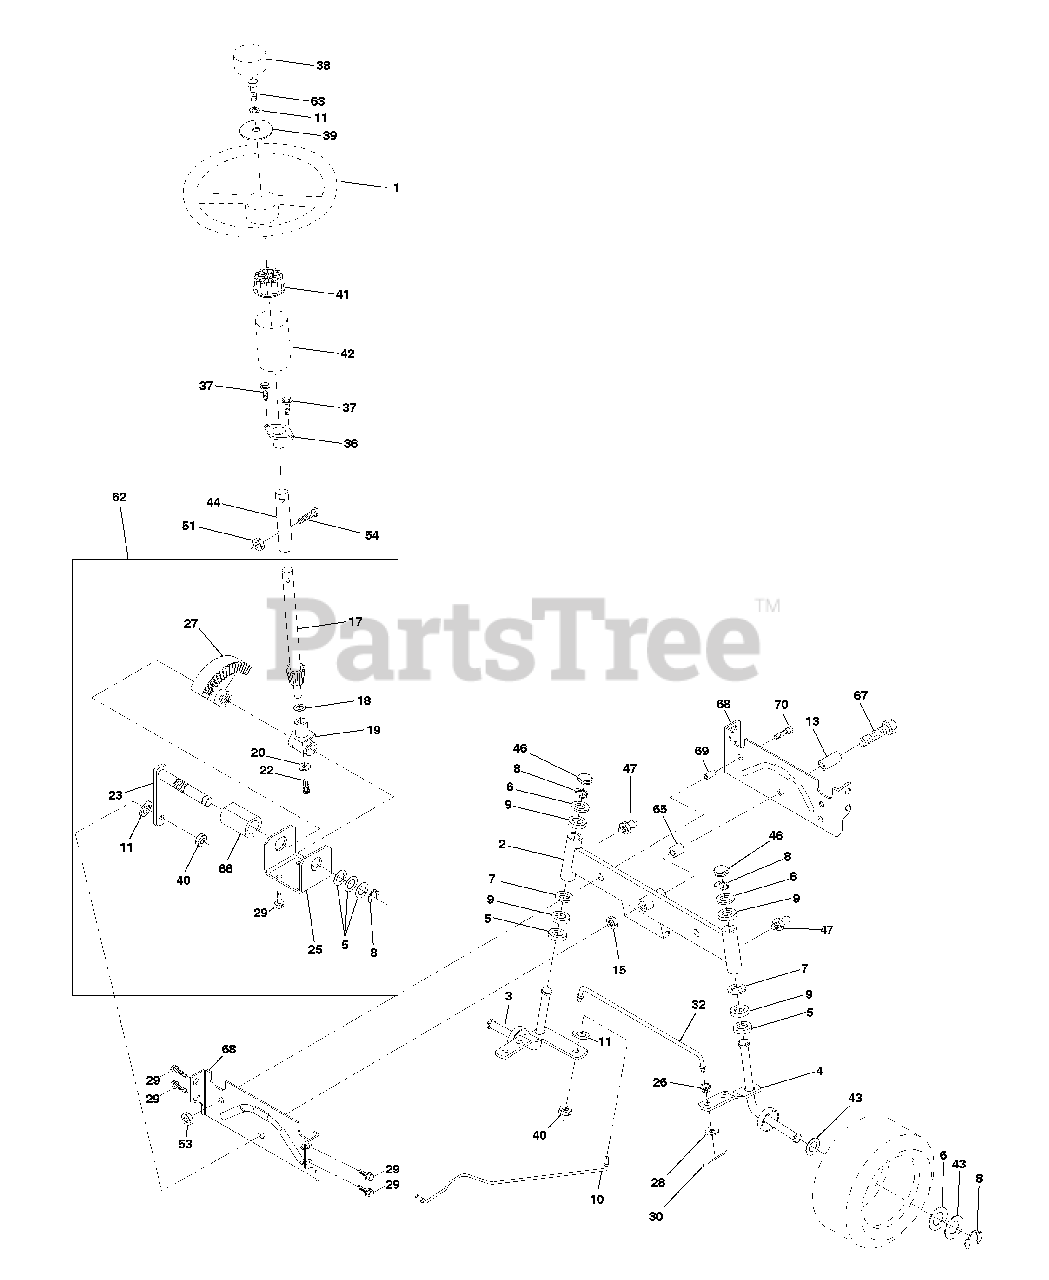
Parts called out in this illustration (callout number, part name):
1	Wheel Steering
2	Axle Asm STMP Dropped STL
3	Spindle Asm LH
4	Spindle Asm RH
5	Bearing Race Thrust Harden
6	Washer 25/32 X 1-5/8 X 16 Ga
7	Washer 27/32 X 1-1/4 X 16 Ga
8	Ring Klip #t5304-75
9	Bearing Col Strg Blk
10	Link Drag Extended Stamp
11	Washer Lock Hvy Hlcl Spr 3/8
13	Bearing Axle STLT/GT
15	Nut Lock Flange 5/8-11 Unc
17	Shaft Asm Strg
18	Washer Thrust 515 x 750 x 033
19	Support Shaft
20	Washer Shim 1/4 X 5/8 X 062
22	Screw Hex Socket 1/4-20 x 5/8
23	Shaft Asm Pittman
25	Bracket Steering
26	Bushing Link Drag Blk LR
27	Gear Sector
28	Washer 13/32 X 7/8 X 16 Ga
29	Screw Thdrol 3/8-16 x 3/4 Ty-tt
30	Pin Cotter 1/8 X 3/4 Cad
32	Rod Tie Wire Form 19 75 Mech
36	Bushing Strg
38	Insert Cap Strg Wh Au
39	Washer 13/32 X 2-3/8 X 8 Ga
40	Lock nut
41	Adaptor Wheel Strg
42	Boot Steering Shaft
43	Washer 25/32 X 1 1/4 X 16 Ga
44	Extension Steering Shaft LR/LT
46	Cap Spindle Fr Top Blk
47	Fitting Grease
51	Nut Lock Hex w/Ins 5/16-18
53	Nut Crownlock 3/8-16unc
54	Bolt Fin Hex 5/16-18 Unc x 1-1/4
62	Kit, Steering Assembly Svc
63	Bolt Fin Hex 3/8-16unc x 1 Gr. 5
65	Spacer Axle
66	Bearing Arm Pittman
67	Bolt, Fin Hex 5/8-11 UNC x 2-3/4
68	Axle, Brace
69	Spacer Brace Axle
70	Bolt Fin Hex 3/8-16unc x 2-1/4
